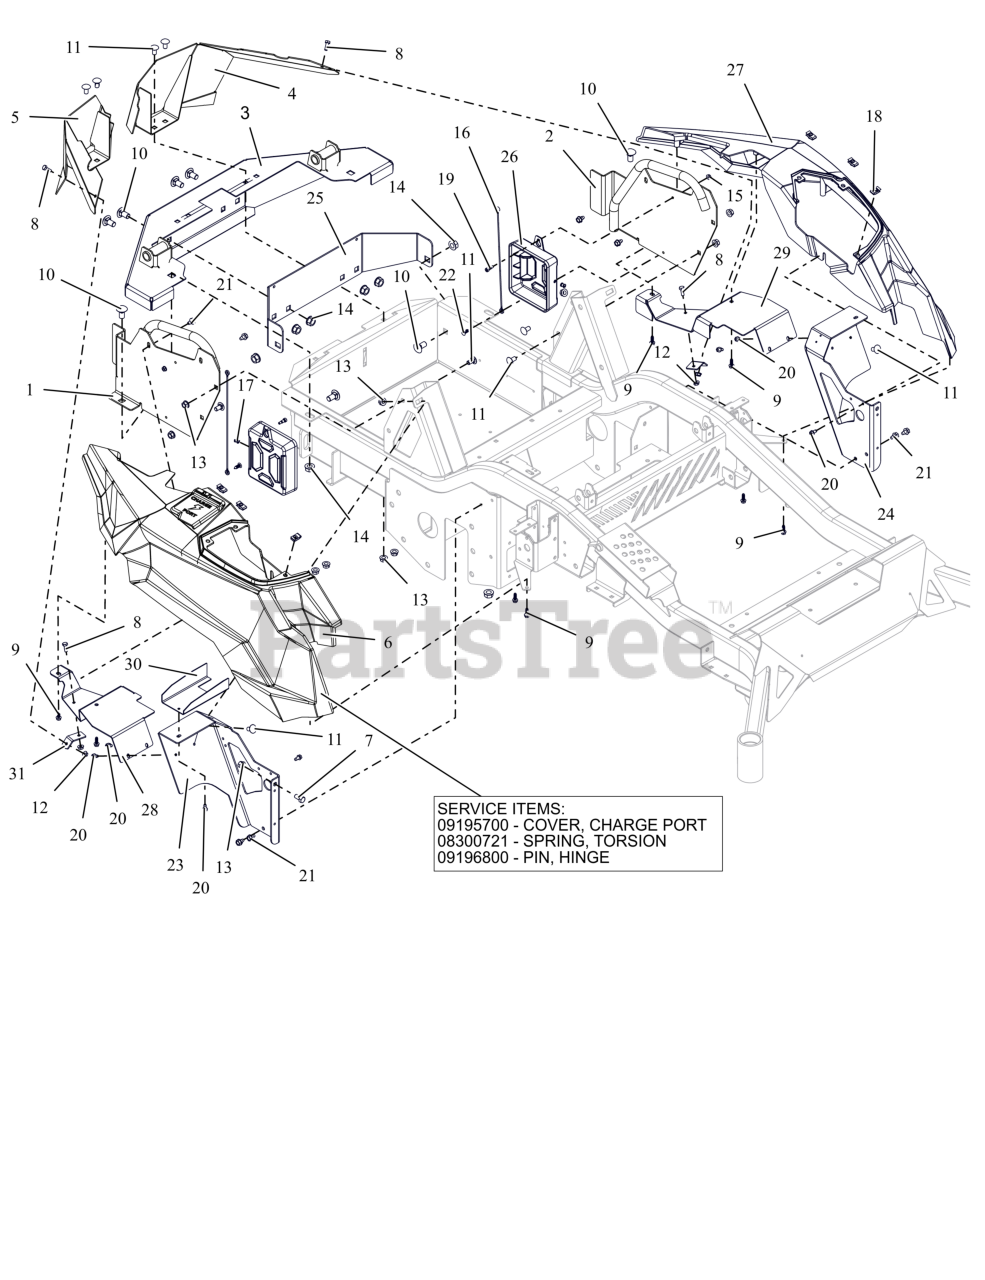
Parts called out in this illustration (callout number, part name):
1	WLDMT, REAR FENDER MOUNT-RH (ORANGE)
2	WLDMT, REAR FENDER MOUNT-LH (ORANGE)
3	WLDMT, BUMPER ZENITH E (ORANGE)
4	WLDMT, REAR WRAP-LH (BLACK)
5	WLDMT, REAR WRAP-RH (BLACK)
6	ASM, FENDER RH PRO-TURN EV
6	COVER, CHARGE PORT
6	SPRING, TORSION
6	PIN, HINGE
7	BLT,HEX .38-16X.75 G5 ZCC
8	BLT, HEX .25-20X.75 G5 ZCC
9	SCR, PLASTITE .25-10X.75 ZCC
10	BLT, RHSN .50-13X1.00 G5 ZCC
11	BTL,RHSSN .375-16 X 0.75 G5 FPB
12	NUT-LK-CTR-FLG .25-20 ZC120
13	NUT-LK-CTR-FLG .375-16 GF ZCC
14	NUT-LK-CTR-FLG .500-13 GG ZCC
15	NUT, FLG-TOP LK #10-24 GF ZCC
16	CABLE, 12.0 LANYARD, NYLON
17	POST, & SCREW, PUSH LOCK .25 X .25
18	NUT-RTNR .25-20X.56
19	BLT-SHLDR .25X.375
20	SCR-TAP .25-20X.50 HWH ZCC
21	SCR,TAP .312-18X.50 HWH TR ZCC
22	RIVET, .25 NYLON PANEL
23	MOUNT, FRONT FENDER-RH (ORANGE)
24	MOUNT, FRONT FENDER-LH (ORANGE)
25	SUPPORT, BUMPER (BLACK)
26	COVER, BATTERY BUSBAR TERMINAL
27	FENDER, LH PRO-TURN EV
28	SHIELD, FENDER MOUNT -RH (BLACK)
29	SHIELD, FENDER MOUNT-LH (BLACK)
30	SHIELD, DEBRIS -CHARGE PORT (BLACK)
31	STRAP, SUPPORT - REAR WRAP (BLACK)
